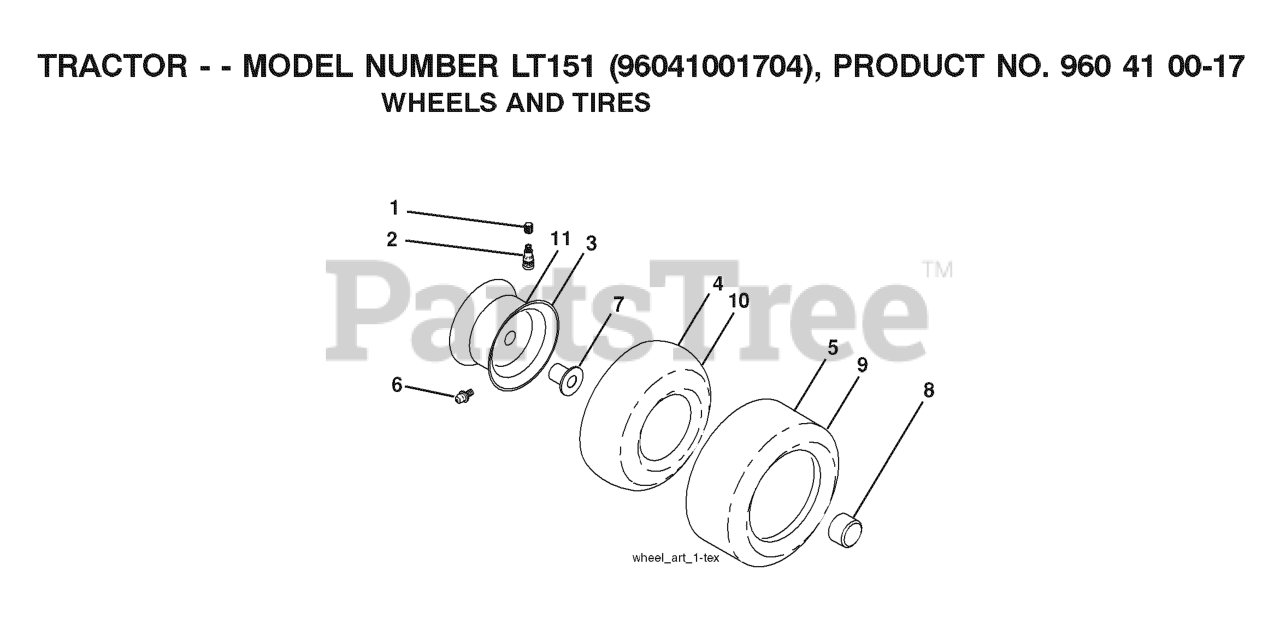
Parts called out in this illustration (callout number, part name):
2	VALVE STEM LT
3	TIRE HEAVY DUTY
4	TUBE.5.3/4.5/6
5	RIM ASM 6" FRONT SILVER
6	FITTING LT
7	BEARING T
8	CAP, AXLE BLK
9	TIRE HEAVY DUTY
10	TUBE
11	RIM ASM 8" REAR SILVER
